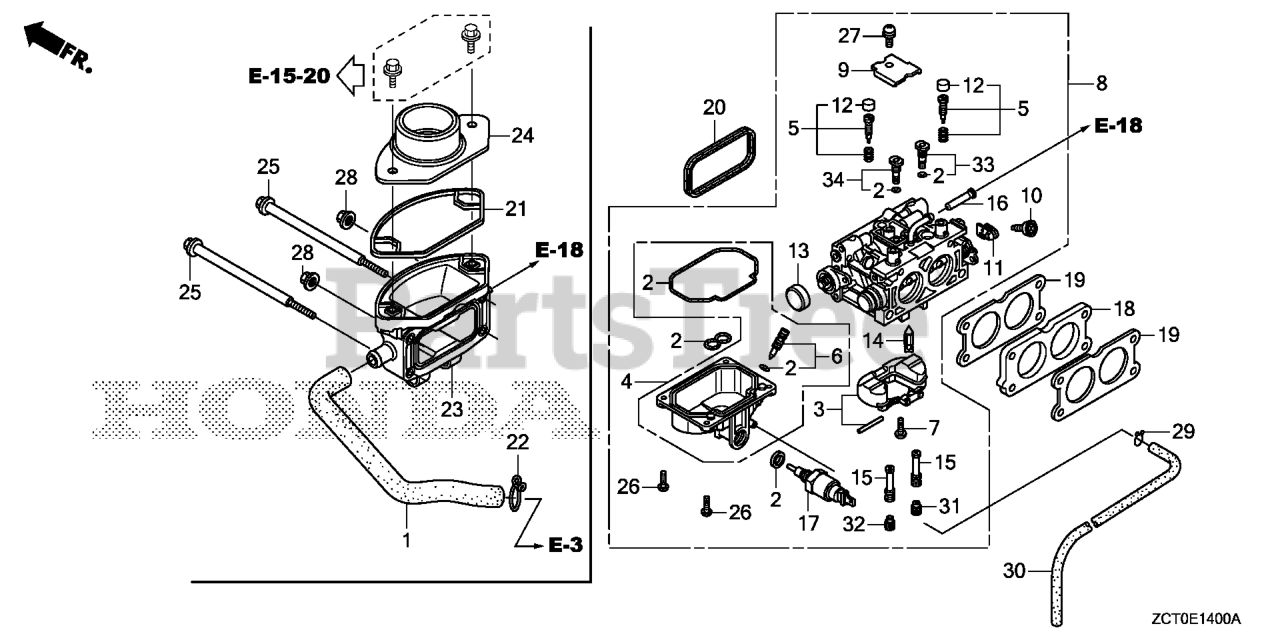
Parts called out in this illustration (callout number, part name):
2	GASKET SET
4	CHAMBER SET, FLOAT
5	SCREW SET (CARBURETOR NO.)
6	SCREW SET, DRAIN (ADVENTURE GREEN) (CARBURETOR NO.)
7	SCREW, FLOAT
8	CARBURETOR ASSY. (BK05P A)
10	SCREW, THROTTLE STOP
11	ARM, THROTTLE LINKAGE
12	CAP, ADJUSTING SCREW (CARBURETOR NO.)
13	CAP, CHOKE LEVER DUST
14	VALVE, FLOAT
15	NOZZLE, MAIN
16	SCREEN, FUEL STRAINER
17	VALVE ASSY., SOLENOID
18	INSULATOR, CARBURETOR
19	GASKET, CARBURETOR
20	GASKET, AIR CLEANER
26	SCREW, PAN (4X12)
27	SCREW-WASHER (5X10)
29	CLIP, TUBE (B8)
30	BULK HOSE, VACUUM (4.5X1000) (4.5X450) (BULK HOSE 95005-45008-10M)
31	JET, MAIN (#110) (CARBURETOR NO.)
31	JET, MAIN (#115)
31	JET,MAIN #120
32	JET, MAIN (#112)
32	JET, MAIN (#118)
32	JET, MAIN (#122)
33	JET SET, PILOT (#45) (CARBURETOR NO.)
34	JET SET, PILOT (#45) (CARBURETOR NO.)
